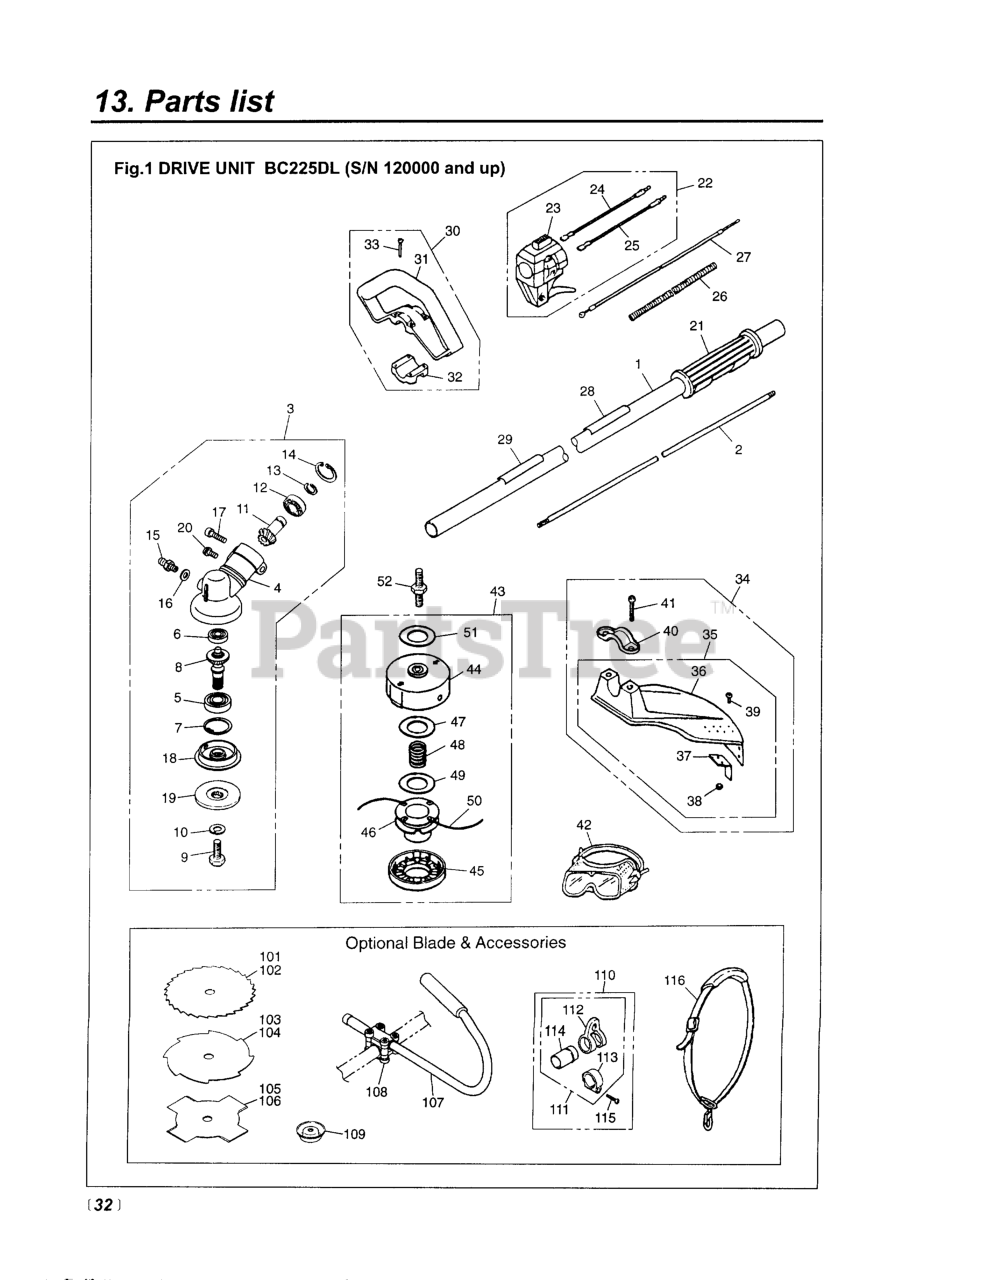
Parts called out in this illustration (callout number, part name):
1	PIPE COMP
2	SHAFT (RPLS -12212)
3	GEARCASE
4	GEARCASE
5	BEARING
6	BEARING
7	RING, SNAP, M26 X 1.2
8	SHAFT COMPLETE
9	BOLT
10	WASHER
14	RING, SNAP, M24 x 1.2
15	FITTING, GREASE
16	WASHER, M6 X .8
17	BOLT, M5 X 20
18	HOLDER (A)
19	HOLDER (B)
20	BOLT, M5 X 10
21	GRIP (RPLS 3577-32140 & 3220-
23	LEVER (USE 848-8R2-0313)
24	CORD (A), BLACK
25	CORD (B), RED
26	TUBE
27	CABLE COMP (RPLS 1633-83100)
28	PLATE, NAME
29	PLATE, CAUTION
30	HANDLE ASSEMBLY
31	HANDLE
33	SCREW, M5 x 35
34	GUARD ASSY (RPLS 6041-24110)
37	BLADE
38	NUT
39	SCREW, M5 x 12
40	CLAMP (REPLACES 5807-24120)
41	BOLT, M6 x 1.30
42	GOGGLE
43	4
44	CASE (RPLS -15112)
45	COVER (RPLS -15130)
46	HOLDER, CORD (RPLS -15141)
47	PLATE, LARGE
48	SPRING (RPLS -99161)
49	PLATE, SMALL
50	CORD
51	SPACER
52	SHAFT
101	BLADE, 9
102	BLADE, 9
103	BLADE, 8
104	BLADE, 9
105	BLADE, 8
106	BLADE, 9
107	HANDLE, J
108	BRACKET ASSY (REPLACES -14100)
109	COVER (RPLS 6460-13280)
110	HANGER ASSEMBLY
111	HANGER COMPLETE
112	HANGER
113	CLAMP
114	SLEEVE
115	SCREW, M5 x 25
